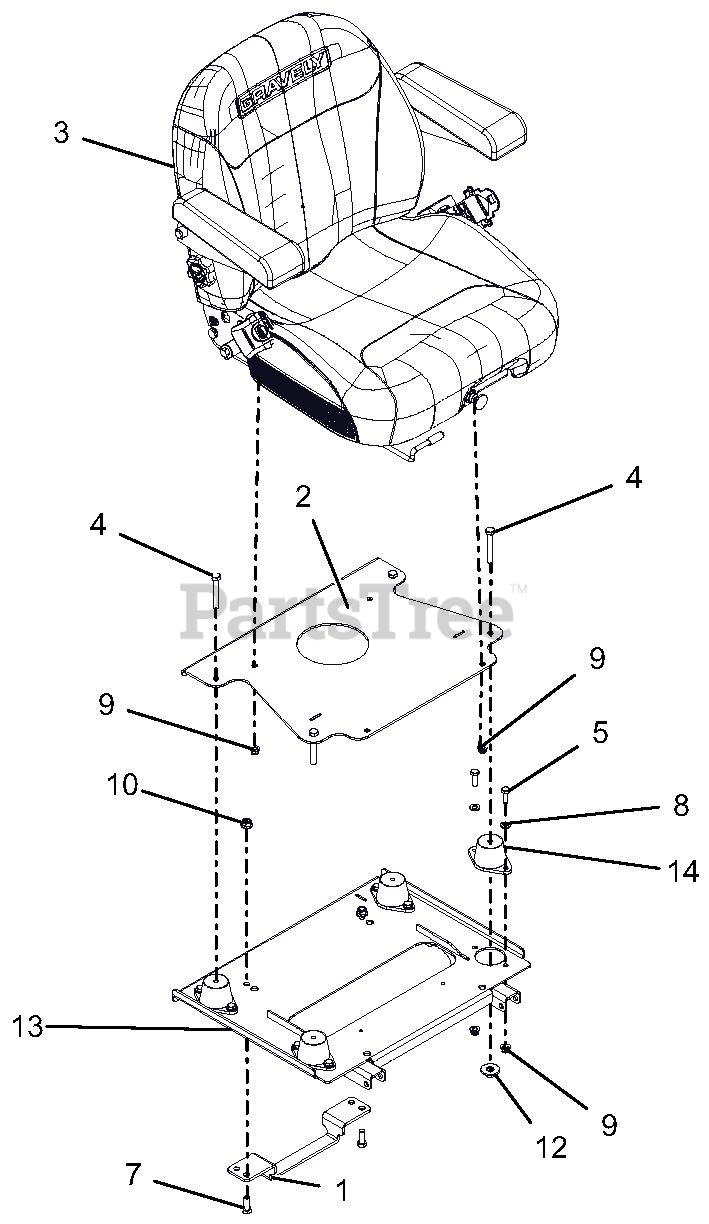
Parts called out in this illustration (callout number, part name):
1	BRKT, SEAT LATCH
2	WLDMT, SEAT MOUNTING
3	SEAT, AIR SUSPENSION
4	BLT-HEX .38-16X2.50 FTH GR5 YWZC
5	BLT-HEX .31-18X1.00 GR5 YWZC
7	BLT-HEX .38-16X1.00 GR5 YWZC
8	WSHR-FL-STL.344X.688X.065YWZC
9	NUT-LK-NYL-FLG .31-18 YWZC
10	NUT-LK-NYL-FLG .38-16 YWZC
12	WLDMT, SEAT RETAINER
13	SEAT ISO MTG WMT W/SAFETY DECALS
14	MOUNT, ISOLATOR
